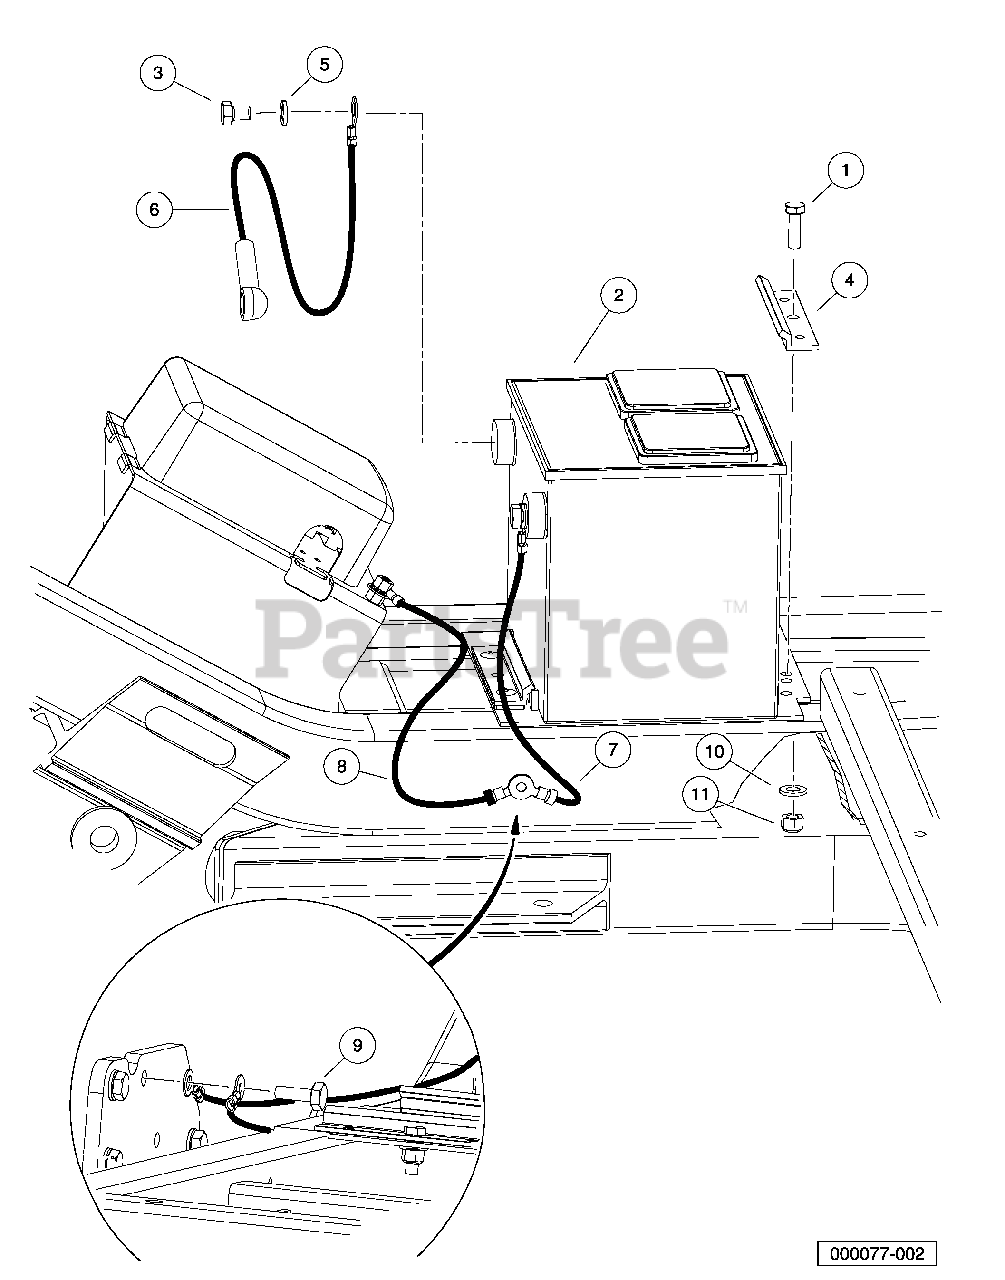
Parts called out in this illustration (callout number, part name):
1	Screw, 5/16-18 X 1.00 Hex Cap
2	Battery, 12-Volt
3	Screw, 3/8-16 X 0.50 Stainless Steel Hex-Head
4	Clamp, Battery
5	Lockwasher, 3/8 Stainless Stl
6	Asm, #6 Red Wire
7	Wire Asm, #6 Blk, Awd, 350
8	Wire Asm, #6 Blk, Awd, 325
9	Bolt, M10 X 1.25 X 25 Loctite
10	Washer, 5/16 Type A Flat
11	Locknut, 5/16-18 Nylon Insert
